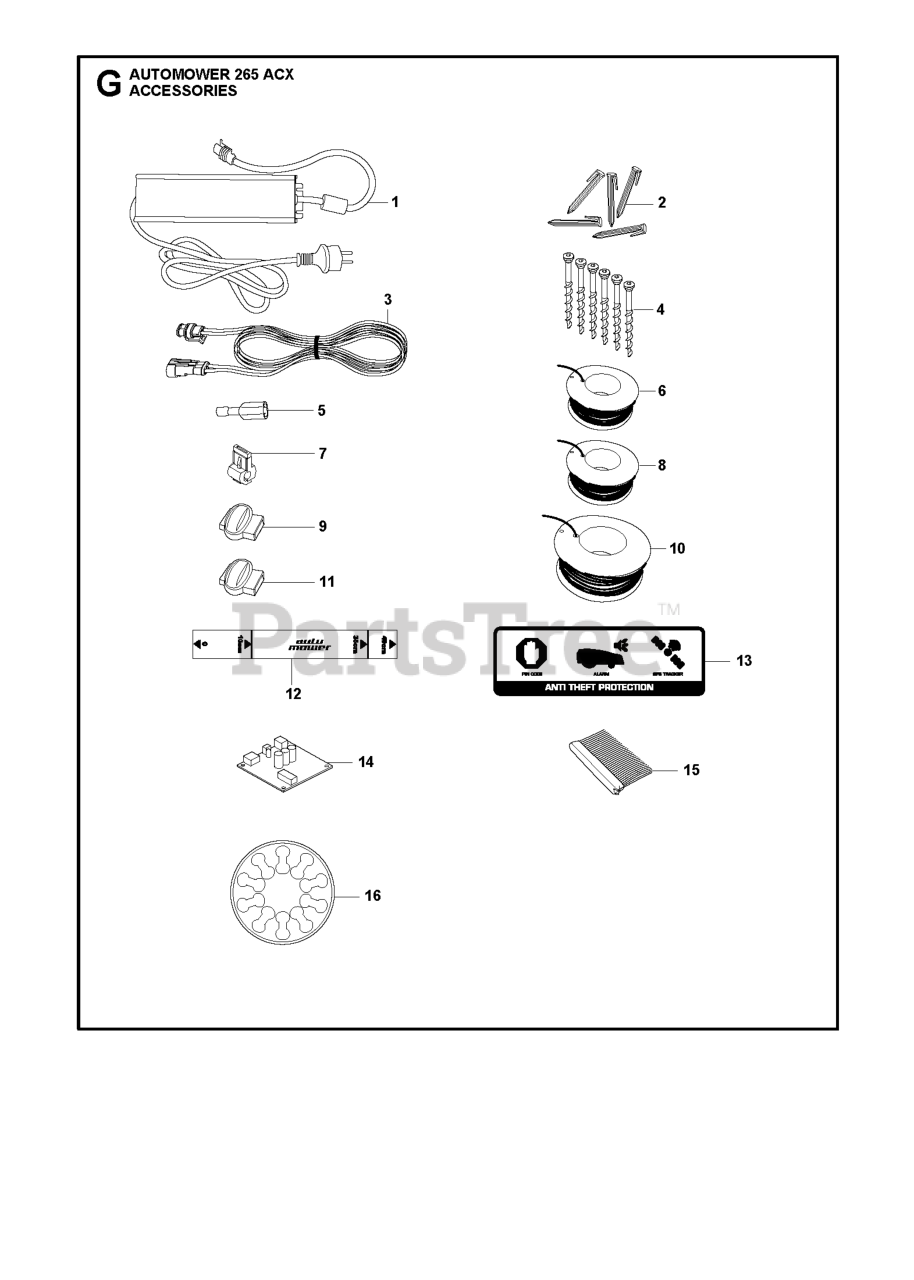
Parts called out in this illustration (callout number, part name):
2	STAPLES (100 CT BAG)
2	STAPLE 100 PCS, BLISTER
4	SCREW 3 PCS, BLISTER PACK
4	SCREW KIT CS
6	LOOP WIRE 150M
6	WIRE 150M, BLISTER
7	CONNECTOR 5 PCS, BLISTER
7	BRAKER
8	LOOP WIRE 250M
9	SPLICE KIT
9	COUPLER SPLICER, 5 PCS,
10	WIRE 500M
11	SPLICE CONNECTOR 50 PCS/PK
14	PRINTED CIRCUIT ASSY
15	BRUSH KIT - ONLY BRUSHES 6 PCS
